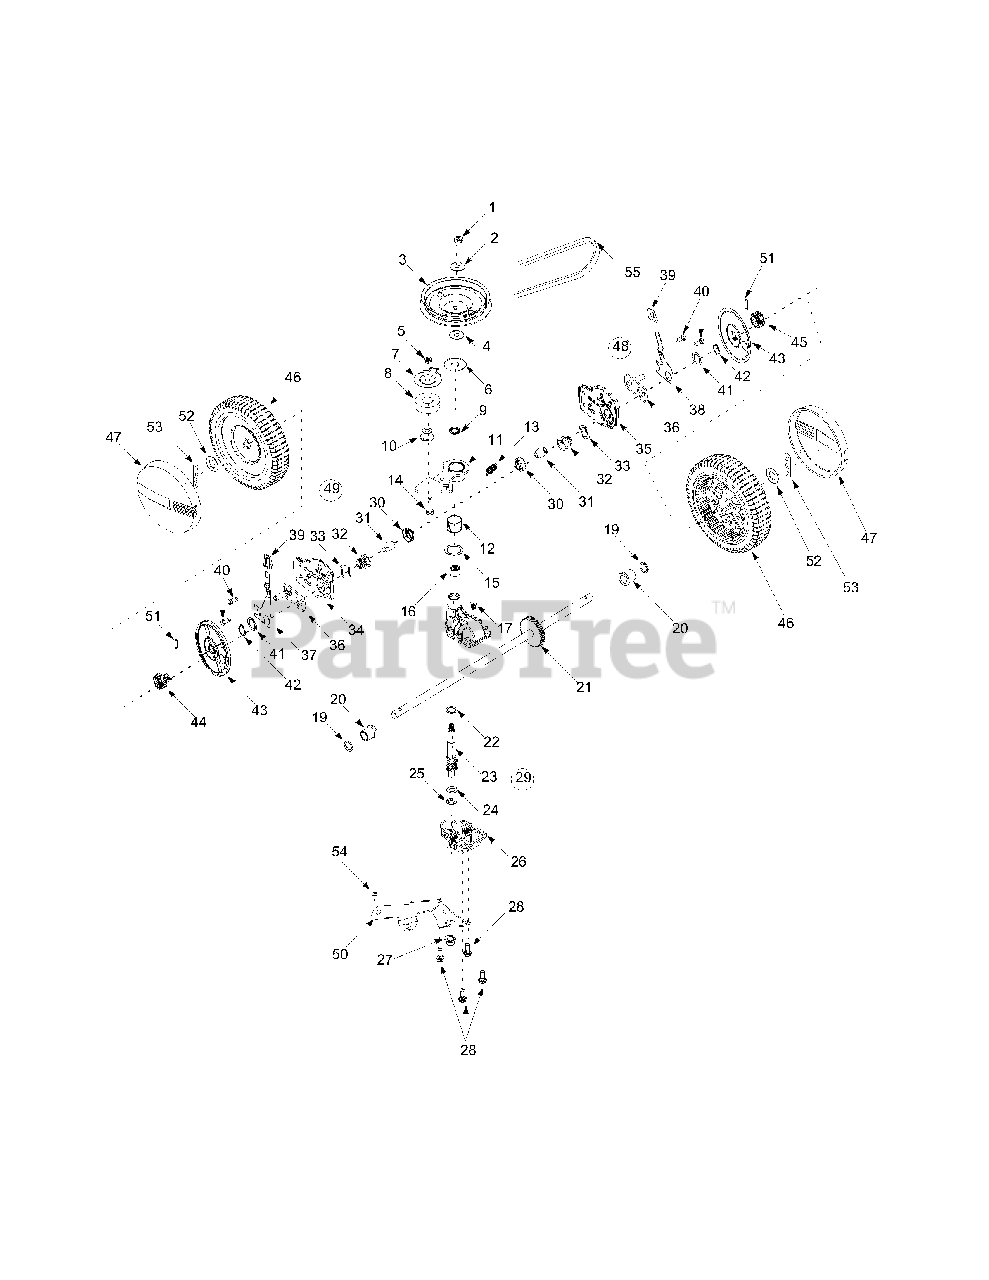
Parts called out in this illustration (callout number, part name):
1	Hex Jam Nut 5/16-24
2	Bell Washer .325 x .930 x .045
3	Pulley 3.82 x .313 x .68
4	Bell Washer .325 x .930 x .045
5	Lock Nut 1/4-28
6	Flat Washer .442 x 1.38 x .060
7	Belt Keeper
8	Ball Bearing
9	Oil Seal
10	Flange Spacer
11	Idler Bracket Assembly
12	Bearing Sleeve
13	Flat Washer .504 x .700 x.030
14	Hex Cap Screw 1/4-28 x 1.00
15	Flat Washer .865 x 1.145 x .030
16	Needle Bearing .438 x .625 x .500
17	Plug 1/4 x .437
18	Upper Housing
19	Oil Seal .500 x .687 x .094
20	Flange Bearing
21	Output Shaft
22	Flat Washer .504 x .700 x .030
23	Pinion Shaft 10T
24	Thrust Washer .375 x .70 x .030
25	Thrust Washer .388 x .625 x .062
26	Lower Housing
27	Flange Bearing .378 x .531 x .370
28	Hex Screw Washer 1/4-20 x .750
29	Transmission Assembly
30	Bearing Retainer
31	Bearing Sleeve .50 I.D.
32	Bearing Support
33	Wave Washer 1.5 x 1.0 x .029
34	RH Height Adjuster Plate
35	LH Height Adjuster Plate
36	Pivot Plate Assembly
37	RH Front Lever
38	LH Front Lever
39	Knob
40	Hex Cap Screw 3/8-16 x .75
41	Washer
42	Snap Ring 1.0 Dia.
43	Wheel Dust Cap
44	Gear 14T RH FWD
45	Gear 14T LH FWD
46	Wheel, 8x2
47	Hubcap
48	RH Height Adj. Complete
49	LH Height Adj. Complete
50	Cable Idler Bracket
51	Dowel Pin
52	Flat Washer 1/2 x 1.00 x .063
53	Cotter Pin .08 x 1.42
54	Screw
